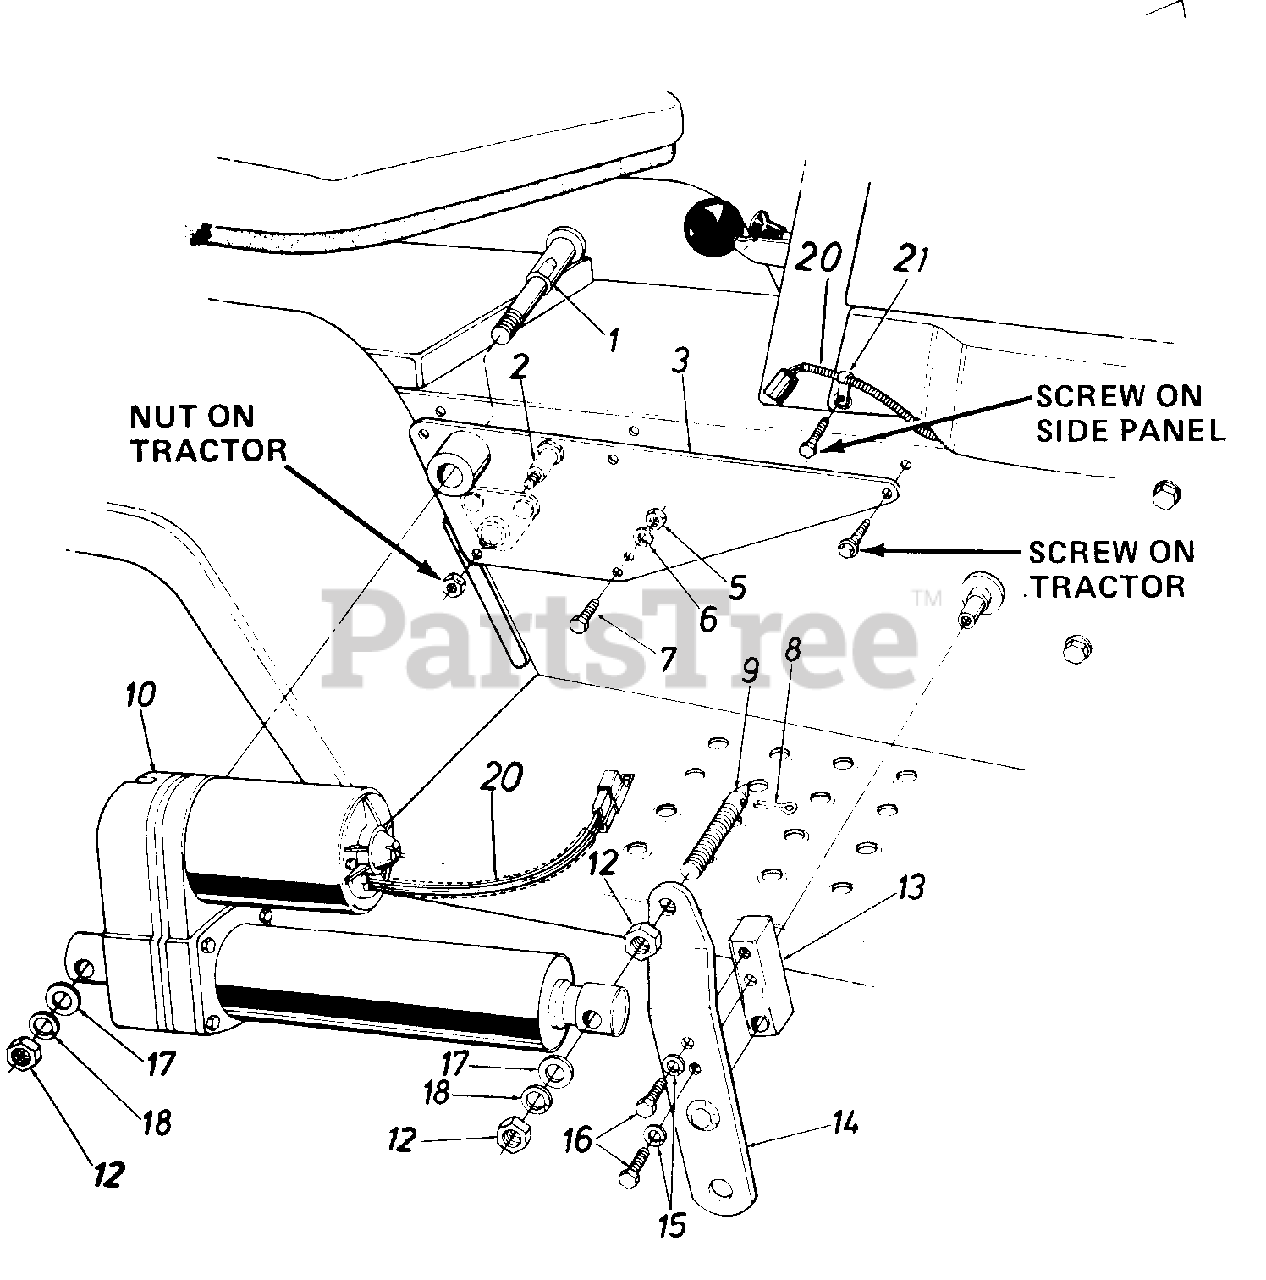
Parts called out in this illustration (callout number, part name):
1	Pivot Pin
2	Shld. Bolt .626 Dia. x .96"
5	Hex Nut 1/4-28 Thd.
6	L-Wash. 1/4" I.D.*
7	Hex Bolt 1/4-28 x .75" Lg. (Grade 5)
8	Cotter Pin
9	Indicator & Mtg. Pin
10	Electric Actuator
12	Hex Jam Nut 1/2-13 Thd.
13	Lift Shaft Drive
16	Hex Bolt 5/16-24 x 1.0" Lg. (Grade 5)
17	Fl-Wash. .53" I.D. x.93" O.D.
18	L-Wash. 1/2" I.D.*
20	Plastic Tubing-7"
21	Clamp
